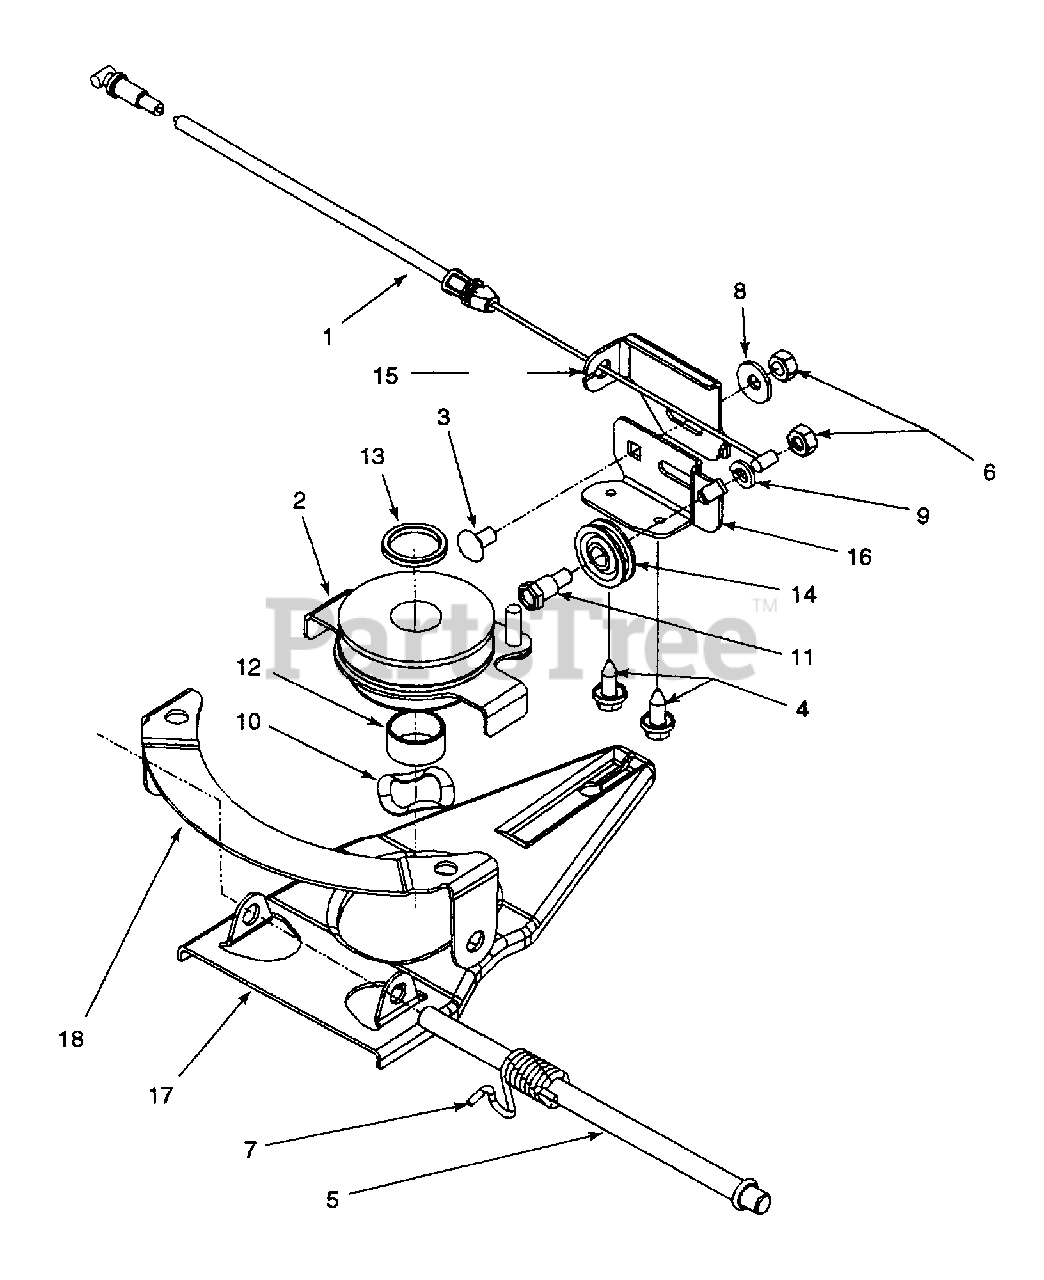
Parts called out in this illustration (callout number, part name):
1	6 Spd. Cable
2	Pulley Ass'y Multi-Spd.
3	Scr. 1/4-20 x .50 Carr.
4	Scr. AB 1/4-14 x .625 Hxinwsh
5	Pivot Shaft
6	Nut 1/4-20
7	Torsion Spring LH
8	Bell Wash. .265 x .75 x .062
9	Lock Wash. 1/4 Reg Duty
10	Wave Wash. 1.38 x .88 x .029
11	Shld. Scr. .375 x 1/4-14AB
12	Slev Spcr .88 ID x 1.00 OD x .48
13	Slev Spcr .88 ID x 1.13 ID x .12
14	Roller Cable
